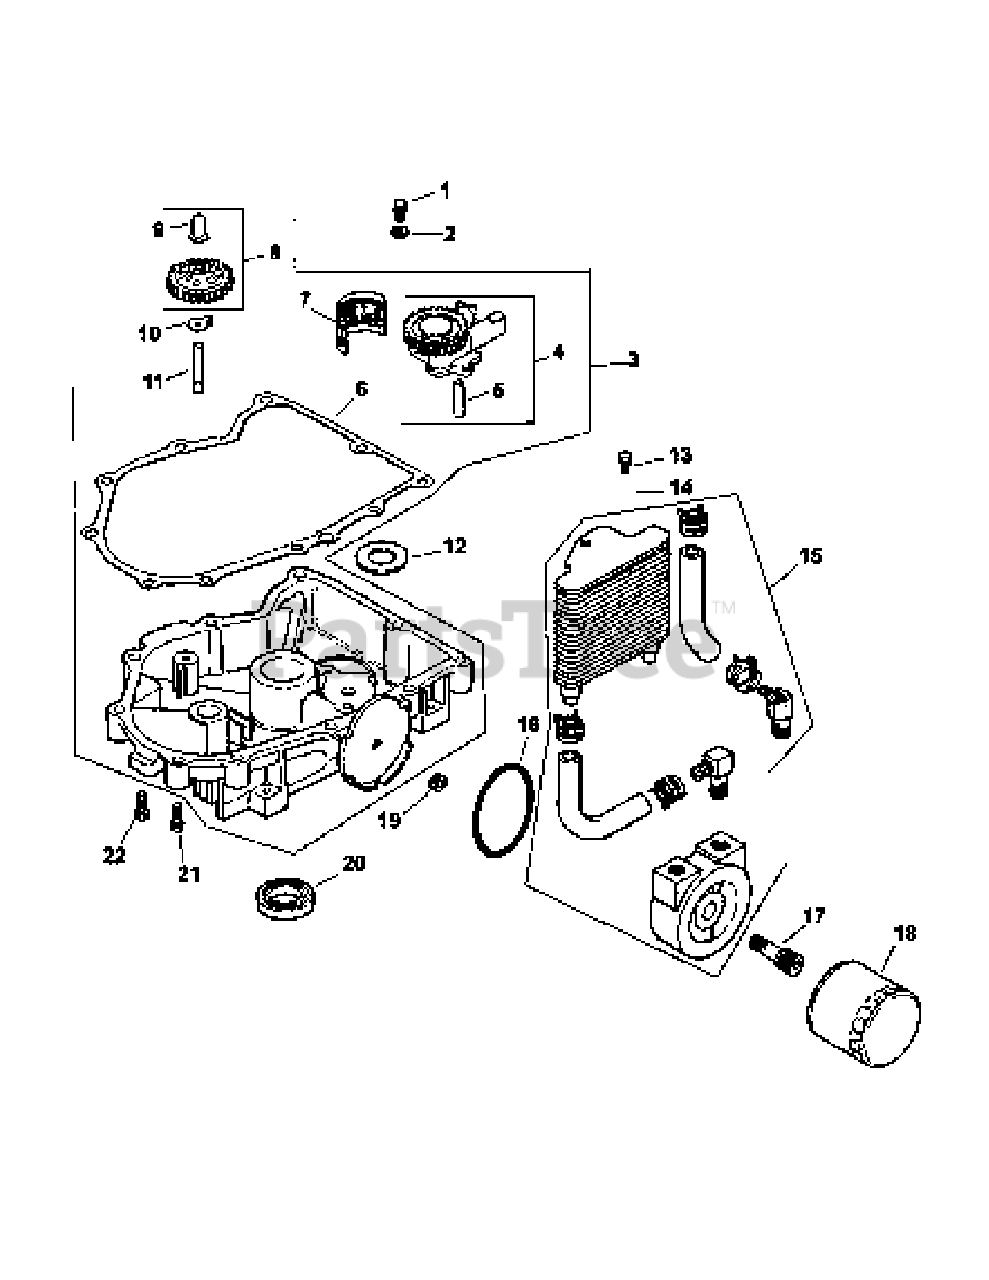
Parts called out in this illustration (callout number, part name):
1	Screw, Hex Flange M6x1.0x25
2	Washer, Plain 6mm
3	Kit, Oil Pan w/Gasket
4	Oil Pump Assembly
5	Tube, Oil Pickup
6	Gasket, Oil Pan
8	Kit, Governor Gear
9	Pin, Governor Regulating
10	Tab, Locking
11	Shaft, Governor Gear
13	Screw, Hex Cap M6x1.7x18
15	Cooler, Oil Phenolic
17	Nipple, Oil Filter
19	Plug, Hex ctsk 3/8"
20	Seal, Oil (PTO end)
21	Screw, Hex Flange M8x1.25x45
22	Screw, Hex Flange M8x1.25x45
23	Plug, Hex hd. 3/8"
24	Switch, Oil Pressure
25	Decal, Oil Sentry (n/s)
26	Decal, Oil Cooler
